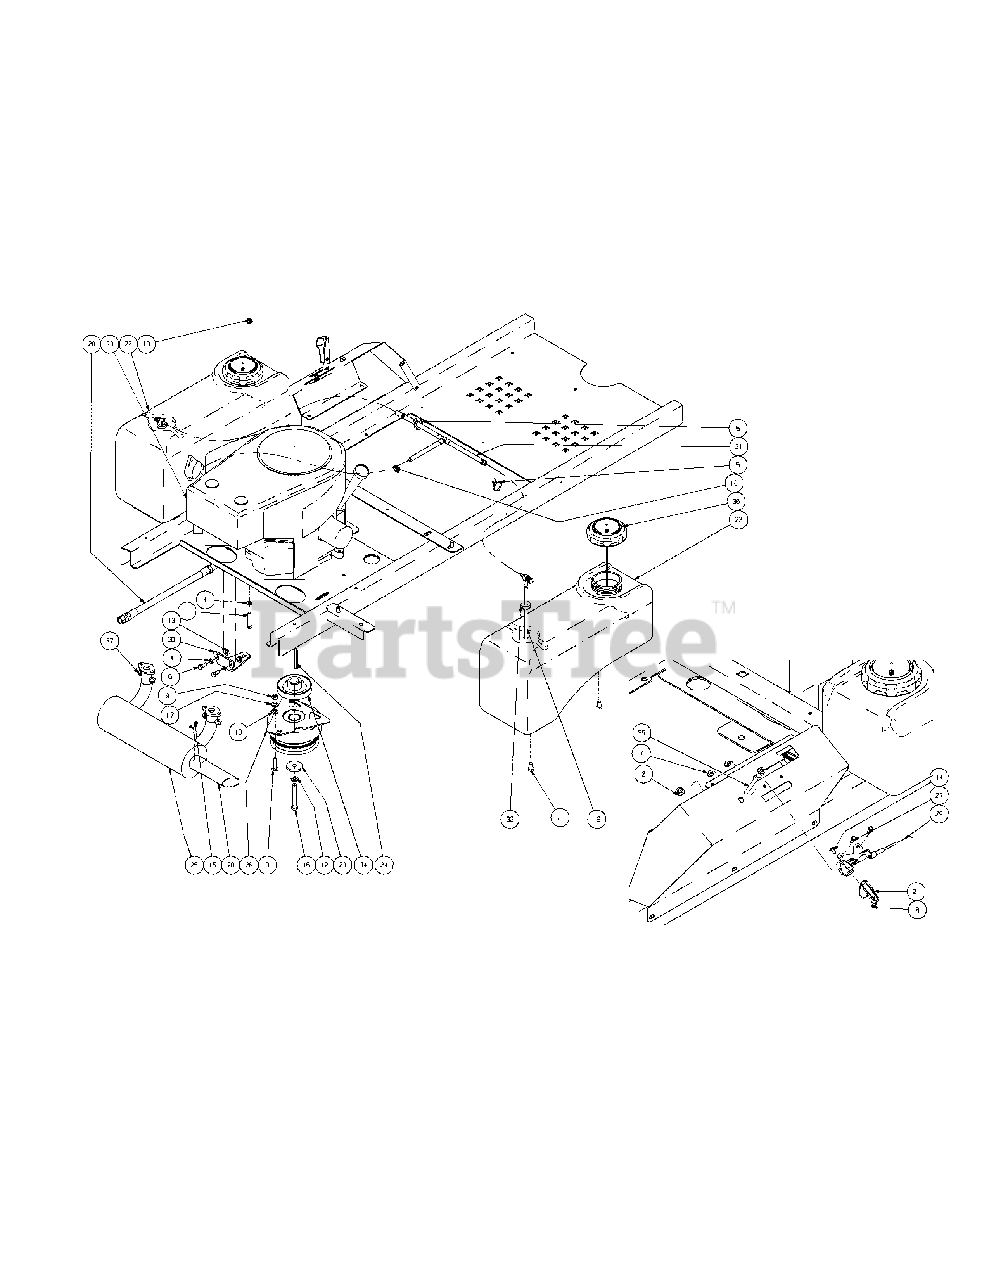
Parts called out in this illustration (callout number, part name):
1	HHCS, 5/16-18, 1-1/2
2	Jam Nut, 3/8-24
3	Carriage Bolt, 5/16-18 x 1.75
4	Flat Washer, 5/16
5	Cable Tie, 3/16 x .05 x 7.4
6	Hex Cap Screw, 5/16-18 x .75
7	Lock Nut, Nylon Insert, 10-32
8	Nut, w/ Star Washer
9	Hex Nut, 5/16-18
10	Hose Clamp, SAE #4: 1/4-5/8, SS
11	Hex Cap Screw, 3/8-16 x .500
12	Lock Washer, 7/16
13	Lock Nut, Hex Flange, 5/16-18
14	Machine Screw, 8-32 x .375
15	Screw, 8-32 x .375, Hex Washer
16	Hex Cap Screw, 7/16-20 x 3.0
17	Lock Washer, 5/16
18	Washer, 3/8 x .738 x .063
19	Fuel Pickup Fitting
20	Oil Drain Extension Hose
21	Throttle Control Knob
22	Fuel Tank
23	Flat Washer, 7/16 ID x 1.75 OD x .250
24	Key, 1/4 x 1/4 x 2.75
25	Kawasaki Muffler
26	Ogura DX11 Electric Clutch
27	Screw, #10-32 x 0.500
28	Exhaust Pipe
29	Throttle Control Cable
30	Clutch Retainer Assembly
31	Fuel Hose Assembly includes:
31	Hose, 1/4" Fuel Line
32	Fuel Tank Groment
33	19HP Kawasaki Engine
34	Transmission Drive Pulley
35	Choke Cable
37	Nut, M8-1.25, Hex Flange
